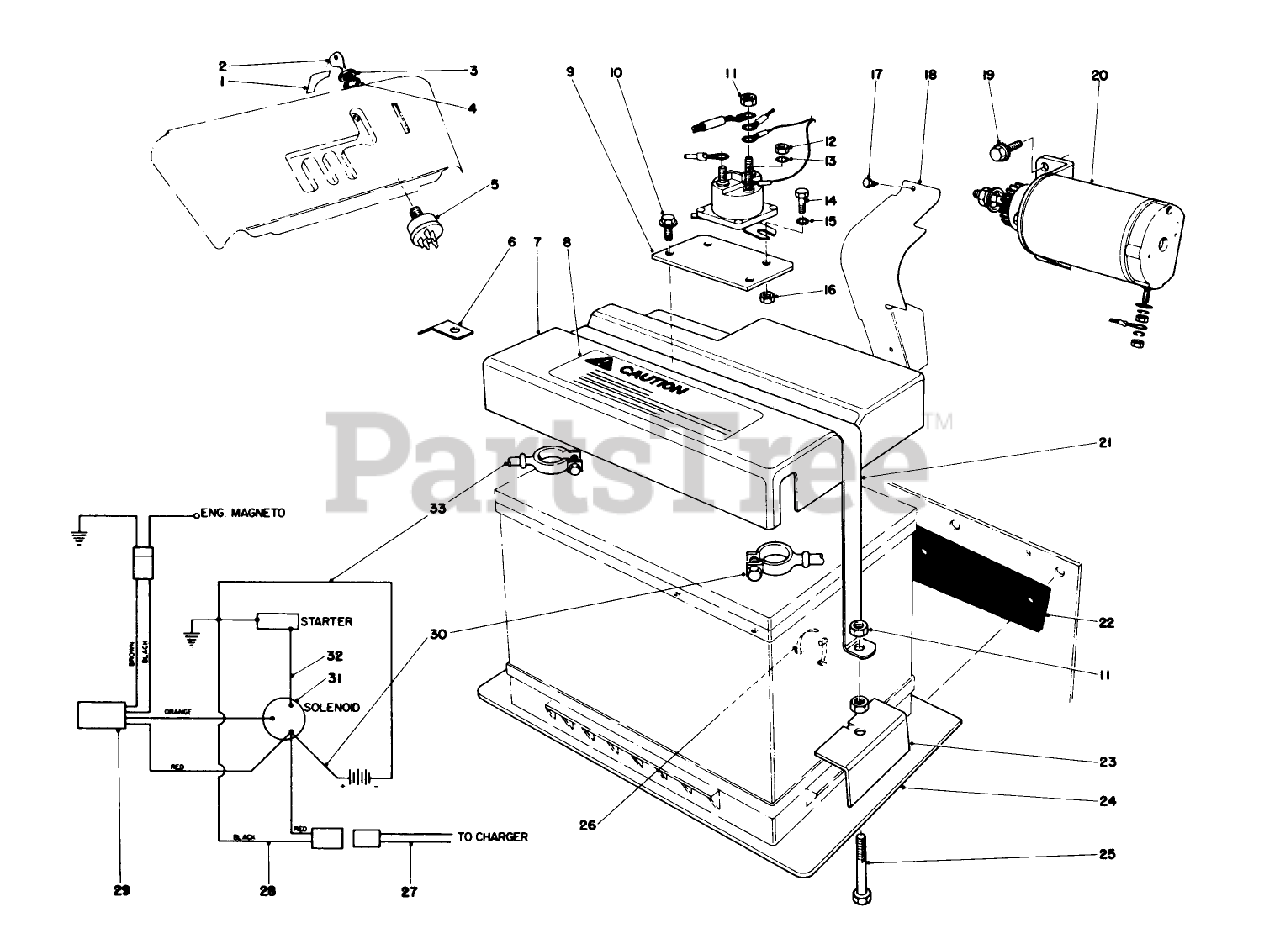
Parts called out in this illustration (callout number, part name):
3	NUT-HH
4	WASHER-LOCK
5	SWITCH-STARTER
10	SCREW-HWH
11	NUT-HEX
12	NUT-HEX
13	WASHER-LOCK, INT
14	SCREW-HH
15	WASHER-LOCK/EXT
16	NUT-LOCK, NI
18	BRIGGS 280265
19	5/16-18X3/4 HX HD SEM
20	Starter Motor Pinion Assy.
25	SCREW-HH
26	TIE-CABLE
27	MALE WIRE ASM
30	BATT-SOLENOID CABLE
31	SOLENOID
